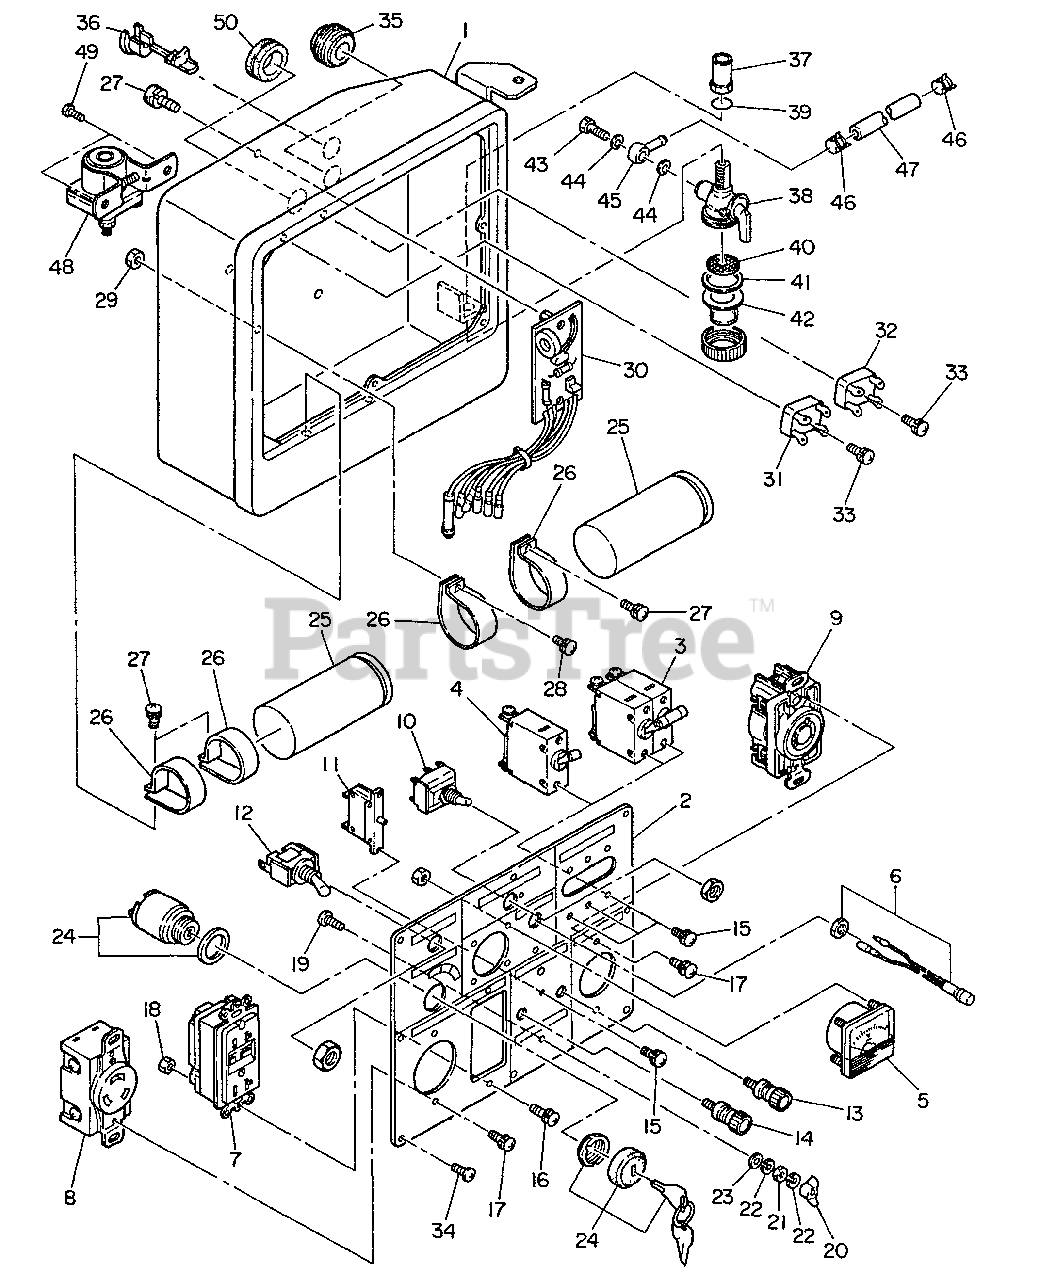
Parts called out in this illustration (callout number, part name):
1	CONTROL BOX ASS'Y
1	CONTROL BOX ASSY
2	CONTROL PANEL ASS'Y
2	CONTROL PANEL
3	NO-FUSE BREAKER (22A X 2)
4	NO-FUSE BREAKER - 30A
5	AC VOLTMETER - 150V
6	LAMP, NEON
7	AC RECEPTACLE - 125V-20A, GFCI
8	AC RECEPTACLE - 125/250V-20A
9	AC RECEPTACLE - 125/250V-20A
10	SWITCH ASSY
11	CIRCUIT BREAKER - 10A DC
13	BOLT, TERMINAL - RED
14	BOLT, TERMINAL - BLACK
15	SCREW
16	SCREW
17	SCREW
18	NUT
19	SCREW
20	WINGNUT
21	NUT
22	LOCKWASHER
23	WASHER
24	KEY SWITCH ASSY
25	CONDENSER ASSY
26	BRACKET, CONDENSER
27	SCREW
28	SCREW
29	NUT
30	IDLE CONTROL UNIT
32	DIODE STACK ASSY
33	SCREW
34	SCREW -- TAPPING
35	GROMMET
36	GROMMET
37	CONNECTOR
38	FILTER, FUEL
39	O-RING
44	WASHER
45	BOLT, BANJO
46	CLAMP, HOSE
47	RUBBER PIPE (6 X 12 X 160mm)
49	BOLT
50	GROMMET
